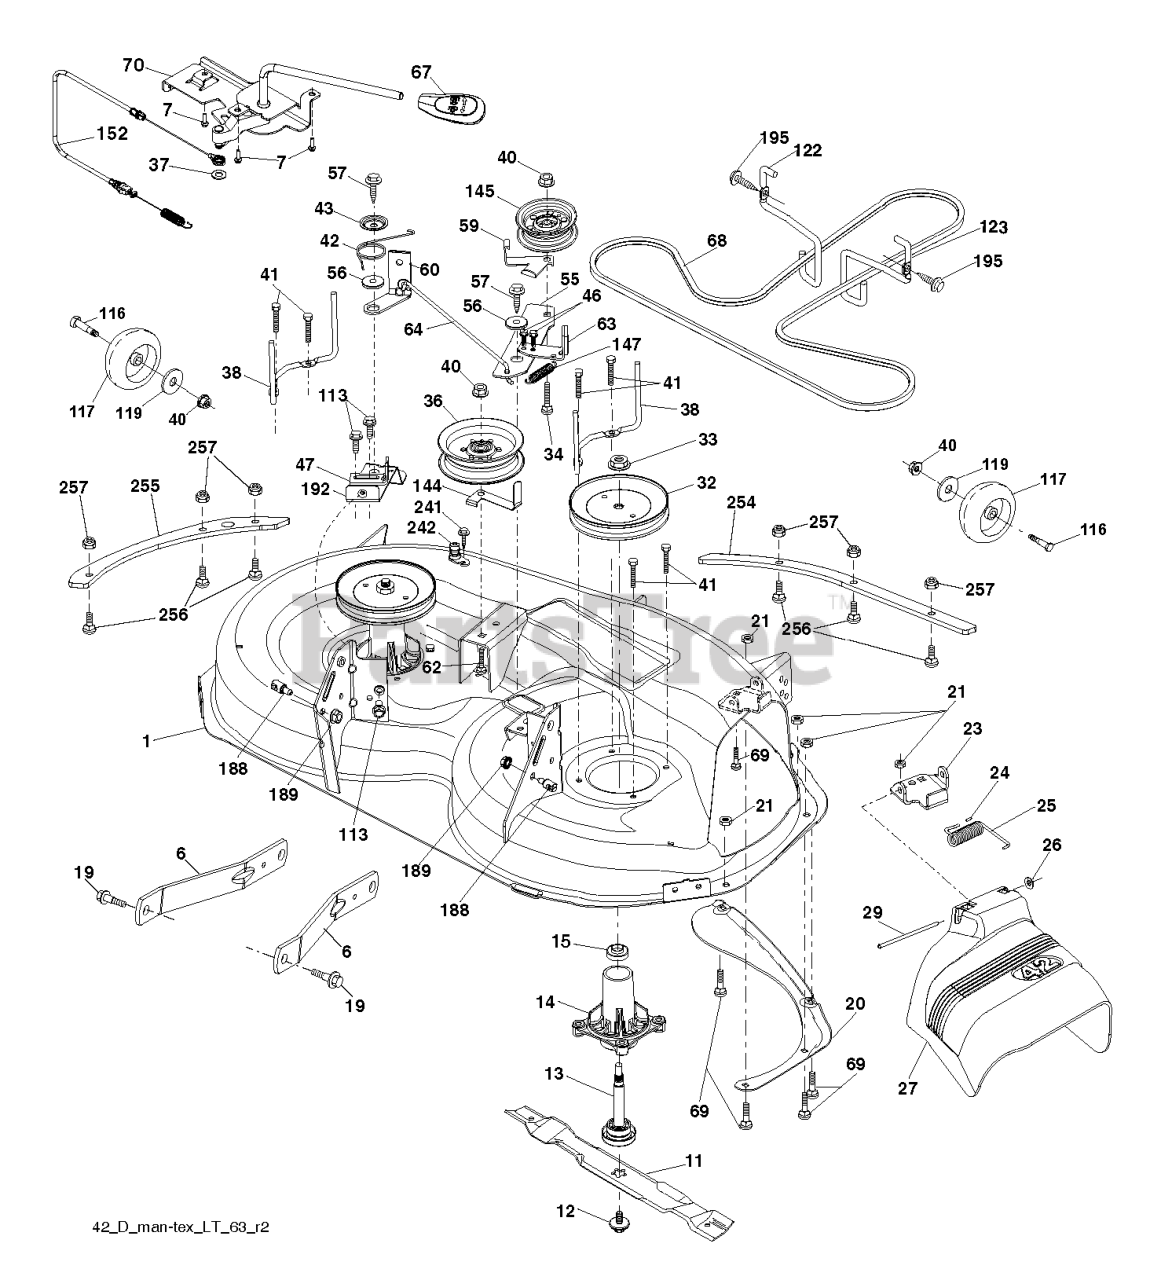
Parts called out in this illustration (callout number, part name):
1	Decks
6	ARM.SUSPENSION.MOWER.R
7	SCREW.#10 X 0.750.BOS
11	42" HI-LIFT BLADE
12	SCREW.SEMS.7/16-20X1.HEX.HEAD
13	SHAFT ASM.MNDRL.N/GREASEABLE
14	RP.HOUSING.MANDREL.4PT.
15	BEARING.MANDREL.TOP.EXTENDED
19	BOLT.SHOULDER
20	BAFFLE.VORTEX
21	LOCKNUT
23	BRKT.DEFLECTOR.38"2005+
24	CAP-SLEEVE LT
25	SPRING.TORSION.DEFLECT
26	NUT PUSH M
27	SHIELD.DEFLECTOR.MOWER.42"BLAC
29	ROD.HINGE
32	PULLEY.MANDREL.5.438.PD
33	NUT.FLANGE.LOCK.TOP
34	BOLT.3/8-16X1.50
36	PULLEY.IDLER.2006
37	WASHER
38	KEEPER.BLT.PNT.MNDRL.PULL.6.25
40	NUT LOCK FLG 3/8-16 UNC
41	BOLT.HEX.WASHR.HED.313-18X1.19
42	SPRING.TORSION.BRAKE
43	SRPING.TORSION.RETAINE
46	SCREW.1/4-20X5/8
47	BRKT.CLUTCH.CABLE
55	IDLER.ARM.42"
56	SPACER.RETAINER
57	SCREW 3/8-16X1
59	GUARD, BELT
60	ARM BRAKE MOWER
63	ARM BRAKE MOWER
64	LINKAGE BRAKE
67	HANDLE.CLUTCH.CABLE.LT
68	BELT.DECK.DRIVE.42"
69	BOLT
70	CLUTCH.ASM.MANUAL.YT.PREDATORQ
113	BOLT.5/16HEX.WHS.HD
116	BOLT.SHOULDER.3/8-16X3-5/8.
117	WHEEL.GAUGE.RALLY
119	WASHER.5/16.FLAT.STE.STD.
122	KEEPER BELT ENGINE LH
123	KEEPER BELT RH
144	KEEPER.BELT.MOWER
145	PULLEY.IDLER.48"PRIMARY
147	RETURN SPRING
152	CABLE.MECHANICAL.CLUTCH
188	STUD.FASTNER.W/ANTI-ROTATE
189	NUT LOCK HEX FLANGE 5/16-18
192	BRKT.BRAKE.STAND.LH.
195	SCREW, 3/8-16X3/4
241	SCREW.TT.#10-32X.5.3/8.FLANGE
242	PORT.WASHOUT
254	PLATES.RENFRC.42DECK.PT431FRNT
255	PLATES.RENFRCE.42DECK.X431SIDE
256	BOLT CUP HEAD SQUARE NECK 1/4-
257	NUT T
